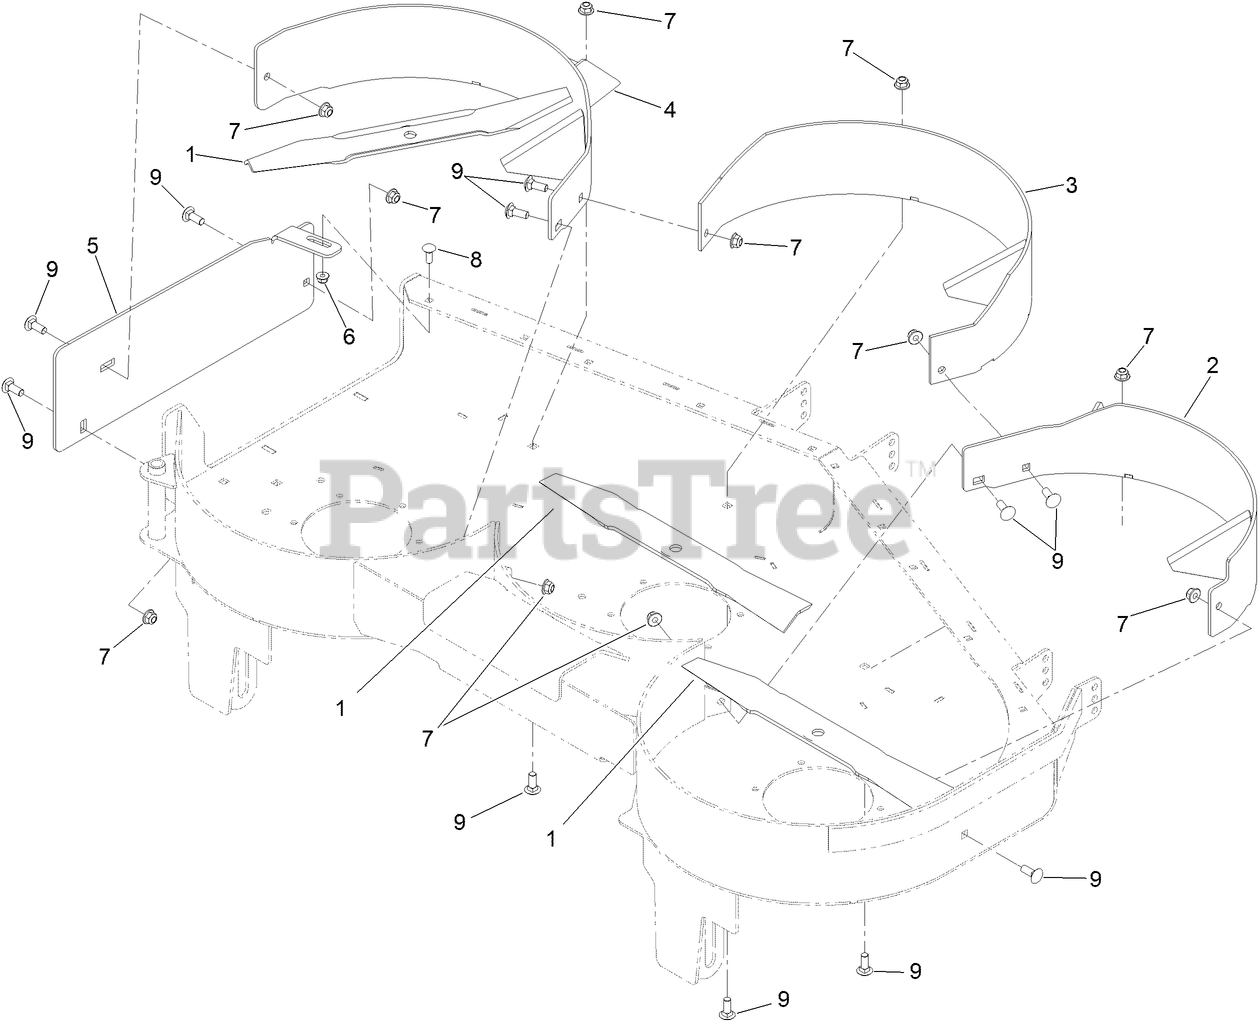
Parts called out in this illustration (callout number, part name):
1	BLADE-MULCH, 18.00 INCH
2	BAFFLE-LH
3	BAFFLE-CENTER
4	BAFFLE-RH
5	PLATE-COVER, DISCHARGE
6	NUT-HF, NI
7	NUT-HF, NI
8	SCREW-CARR
9	BOLT-CARR
